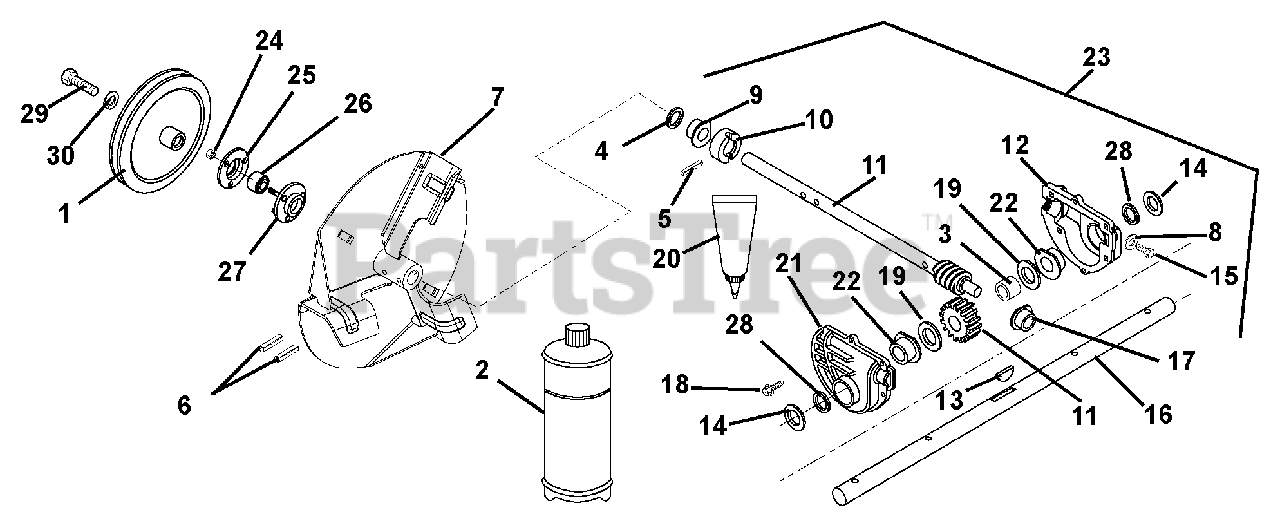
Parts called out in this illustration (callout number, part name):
1	PULLEY, 4L W/HUB, .75 X 8.5
2	ARIENS 16 OZ.BOTTLE OF L2 LUBE
3	BSHG-SLV .755X1.500X.442
4	SEAL-OIL.748X1.378X.276 RBR OD
5	@PIN-GRV .188X1.25 TP E ALLOY
6	PIN-ROLL .250X1.75
7	WELDMENT, IMPELLER,12" 3 BLADE
8	WSHR-FIBER .437X.656X.032
9	BSHG-FLG .750X1.000X.750X1.250
10	THRUST COLLAR, .75" ID
11	SHAFT AND WORM GEAR ASSEMBLY
12	GEARCASE CASTING, MACHINED LH
13	KEY-WDRF .188X.625X.25 SAE 61
14	@WSHR-FL-STL.812X1.50X.135YWZC
15	SCR-TAP .38-16X.75 ROLOK YZ WX
16	SHAFT, RAKE - 24" (.750 DIA)
16	SHAFT, RAKE - 20" (.750 DIA)
17	BSHG-FLG .502X1X.750
18	@SCR-TAP .25-20X1.00 HWH TR YZ
19	WSHR-HDND-THRST .755X1.40X.062
20	LOCTITE 518 GASKET--6ML TUBE
21	GEARCASE CASTING, MACHINED RH
22	BSHG-FLG .753X1.127X.500X1.501
23	GEARCASE, 24" ALUM, SMALL CD
23	GEARCASE, 20" ALUM, SMALL CD
24	@NUT-LK-CTR .25-20 YWZC
25	BEARING FLANGE
26	BRG-BALL .750X1.750X.50
27	BEARING FLANGE
28	SEAL-OIL .750X1.375X.250
29	BLT-HEX .31-24X1.0 GR5 YZ EP80
30	WSHR-LK .312X.097 HVY YWZC
